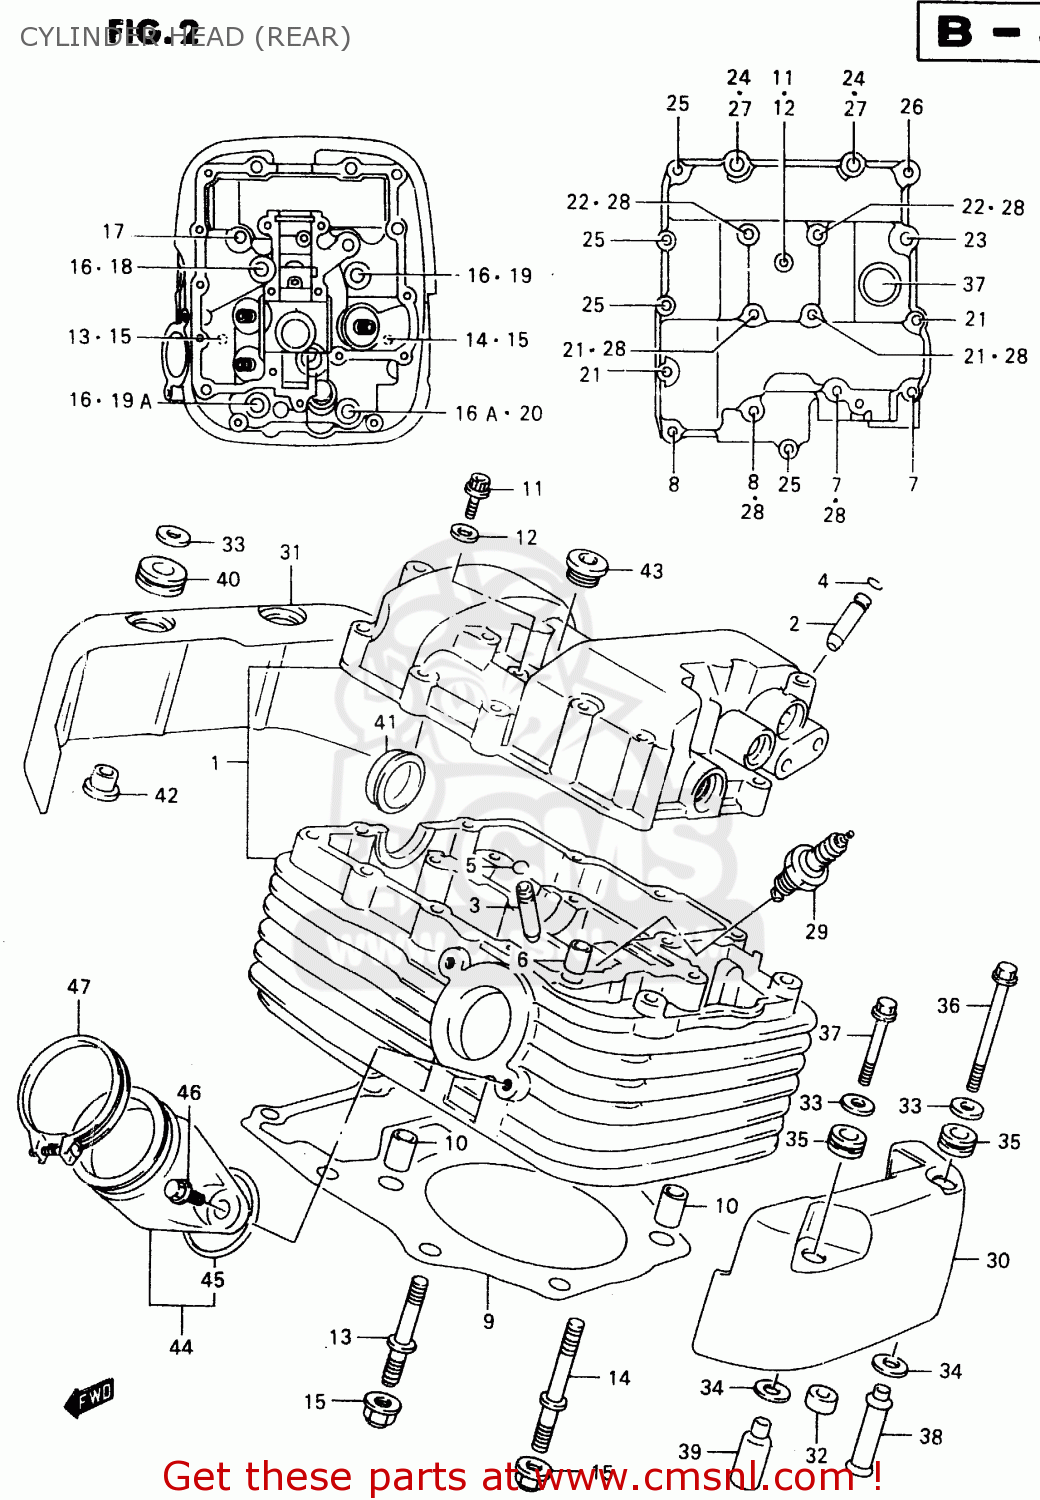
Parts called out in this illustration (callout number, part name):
1	HEAD ASSY,CYLINDER RR
2	GUIDE,INTAKE VALVE
3	GUIDE,INTAKE VALVE
4	RING,SNAP
5	RING,SNAP
6	PIN(6.2X8X11)
7	BOLT(6X60)
8	BOLT(6X55)
9	GASKET,CYLINDER HEAD RR (NAS)
10	PIN
11	BOLT
12	GASKET(6.2X13X1.2) (NAS)
13	BOLT,STUD
14	BOLT,STUD
15	NUT
16	WASHER (10.5X22X2.3)
16A	GASKET(10.5X22X2) (NAS)
17	BOLT(8X57)
18	BOLT(10X180)
19	BOLT(10X190)
19A	BOLT(10X200)
20	BOLT(10X215)
21	BOLT(6X50)
22	BOLT(6X45)
23	BOLT(8X130)
24	BOLT(8X268)
25	BOLT
26	BOLT
27	WASHER(8.5X24X1.6)
28	GASKET(5.8X13X1.2) (NAS)
29	PLUG,SPARK(DPR7EA-9)
30	CAP,CYLINDER HEAD COVER RR,L
31	CAP,CYLINDER HEAD COVER RR,R
32	CUSHION,R CAP
33	WASHER(6.5X18X1.6)
34	WASHER(9.5X20X1)
35	CUSHION
36	BOLT
37	BOLT
38	SPACER,CYL HEAD COVER CAP NO.1
39	SPACER,CYL HEAD COVER CAP NO.2
40	CUSHION
41	PLUG(OD:30)
42	BUSH
43	PLUG,22X11
44	PIPE ASSY,INTAKE RR
45	O RING(D:1.9,ID:40.7)
46	BOLT(6X16)
47	CLAMP
